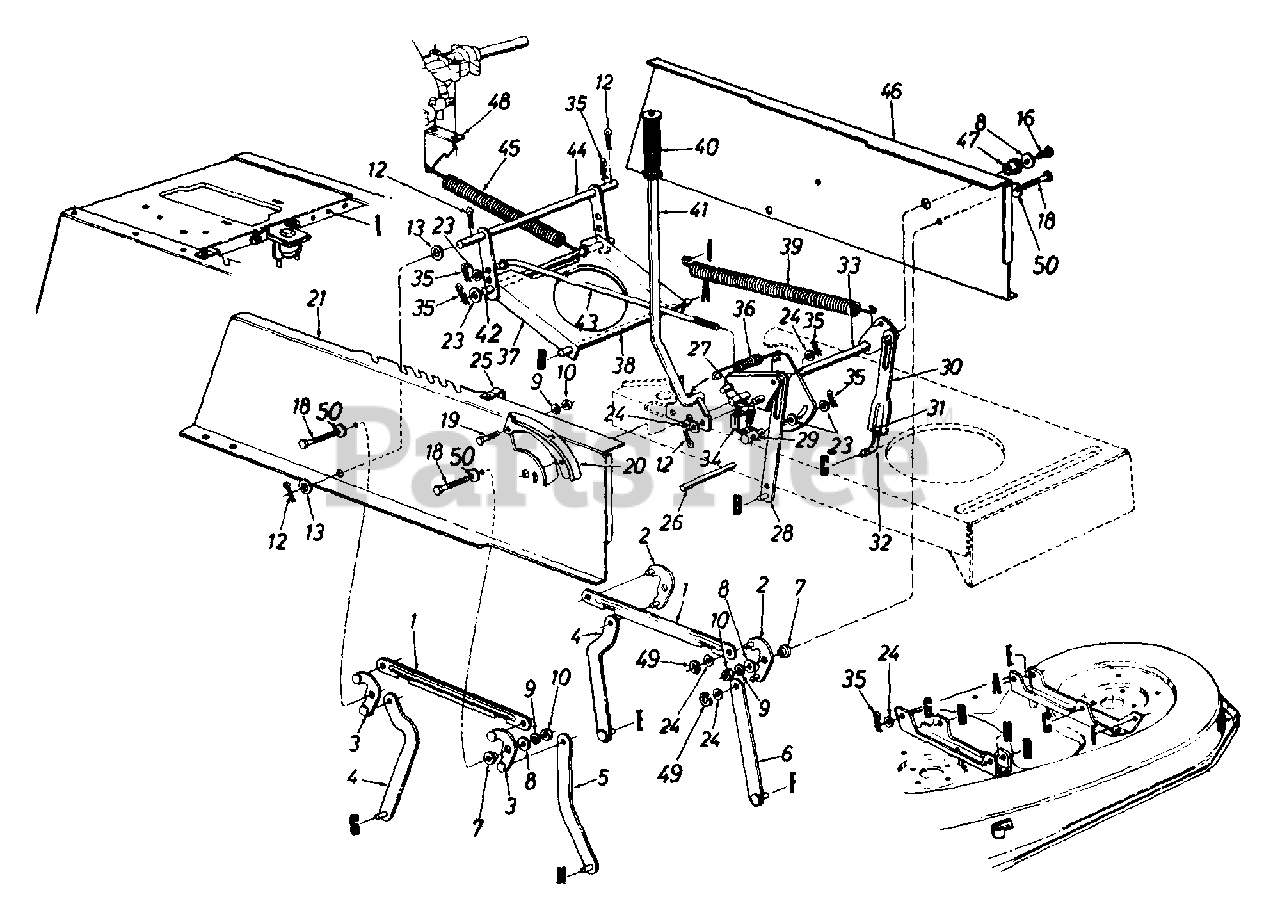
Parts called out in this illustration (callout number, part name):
3	Pivot Link Ass'y. - R.H.
7	Shld. Spacer .318" I.D.
8	Fl-Wash. .344" I.D. x .62" O.D.
9	L-Wash. 5/16" I.D.
10	Hex Nut 5/16-18 Thd.
12	Cotter Pin 1/8" Dia.
13	Fl-Wash. .635" I.D. x 1.0" O.D.
16	Hex Wash. TT-Tap Scr. 5/16-18 x .75" Lg.
18	Hex Wash. Hd. Scr. 5/16-18 x .875" Lg.
19	Hex Bolt 5/16-18 x .75" Lg.
24	Fl-Wash. .531" I.D. x .93" O.D.
26	Running Board Rod
27	Hex Wash. Hd. Tap Scr.
31	Hex Nut 1/2-20 Thd. (Gr. 5)
32	Lift Link Adjuster
33	Lift Shaft Ass'y.
34	Safety Switch
35	Inter. Cotter Pin 3/8" Dia.
36	Extension Spring
39	Extension Spring
40	Grip (Lift Handle)
41	Deck Lift Handle Ass'y.
42	Shaft 3/8" Dia. x 9.34" Lg.
43	Disengagement Rod
44	Stabilizer Shaft Ass'y.
45	Extension Spring 7.58" Lg.
48	Spring Retainer Brkt.
49	"E"-Ring
50	Bell-Wash. .325" I.D.
